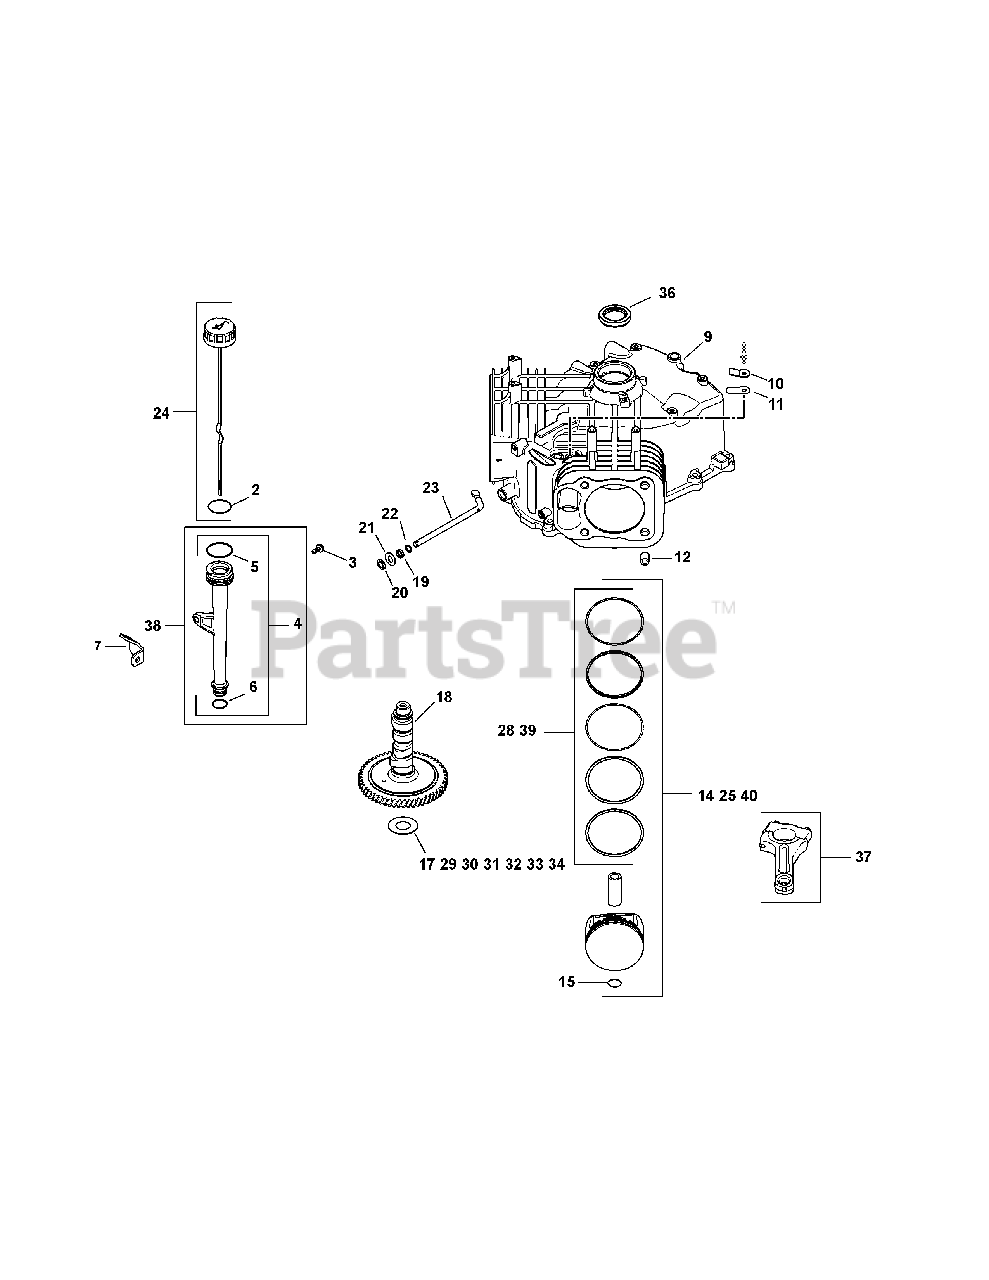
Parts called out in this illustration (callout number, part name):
2	Dipstick Assembly (Includes 2)
3	Flg. Thd. Frm. Screw, M5 X 0.8 X 13
7	Oil Fill Tube Bracket
10	Breather Reed Retainer
11	Breather Reed
14	Piston Kit w/ Ring Set (Inc. 15, 16)
15	Piston Pin Retainer
17	Camshaft Shim (White .028")
18	Camshaft Kit (Inc. KH-25-357-14-S)
19	Governor Cross Shaft Seal
20	Ring Retainer
21	Flat Washer, 9 Mm
22	Flat Washer, 11/32
23	Governor Cross Shaft
24	Dipstick Assembly (Inc. 2)
25	Piston Kit w/ Ring Set (0.25) 83mm
28	Ring Set (.25)
29	Camshaft Shim (Blue .03")
30	Camshaft Shim (Red .032")
31	Camshaft Shim (Yellow .034")
32	Camshaft Shim (Green .036")
33	Camshaft Shim (Gray .038")
34	Camshaft Shim (Black .04")
36	Oil Seal (Helix Lip)
37	Connecting Rod (Std)
38	Tube Assembly (Inc. 4-6)
39	Ring Set (Std)
40	Use KH-24-874-27-S Kit
